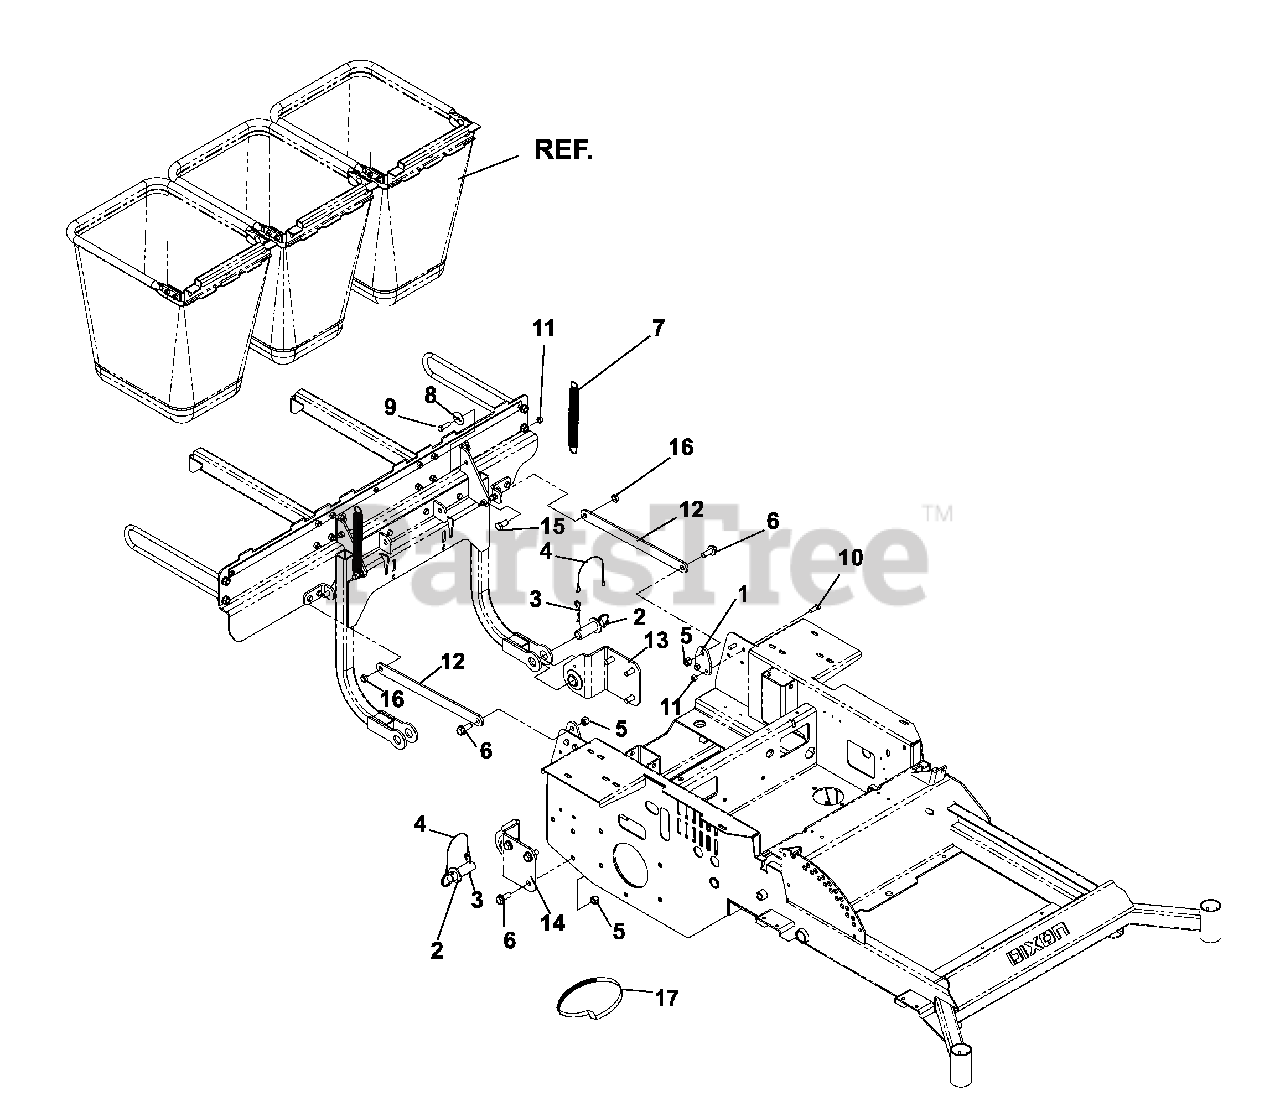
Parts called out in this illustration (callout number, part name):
1	SUPPORT BRACKET
2	HITCH PIN
3	HAIRPIN
4	LANYARD
5	NUT 1/2-13 HEX NYLOC ZD
6	HCS 1/2C X 1 1/4 SERRATED HEAD
8	WASHER, FRICTION
9	HCS 3/8C X 1 1/4 GR5
10	HCS 3/8C X 1
11	NUT 3/8-16 NYLOC
13	HITCH BRACKET WLDMT
14	HITCH BRACKET WLDMT, RT, LRG
15	HHCS 1/2-13 X 1
16	NUT, 1/2-13 THIN PROF NYL
17	HOSE CLAMP
